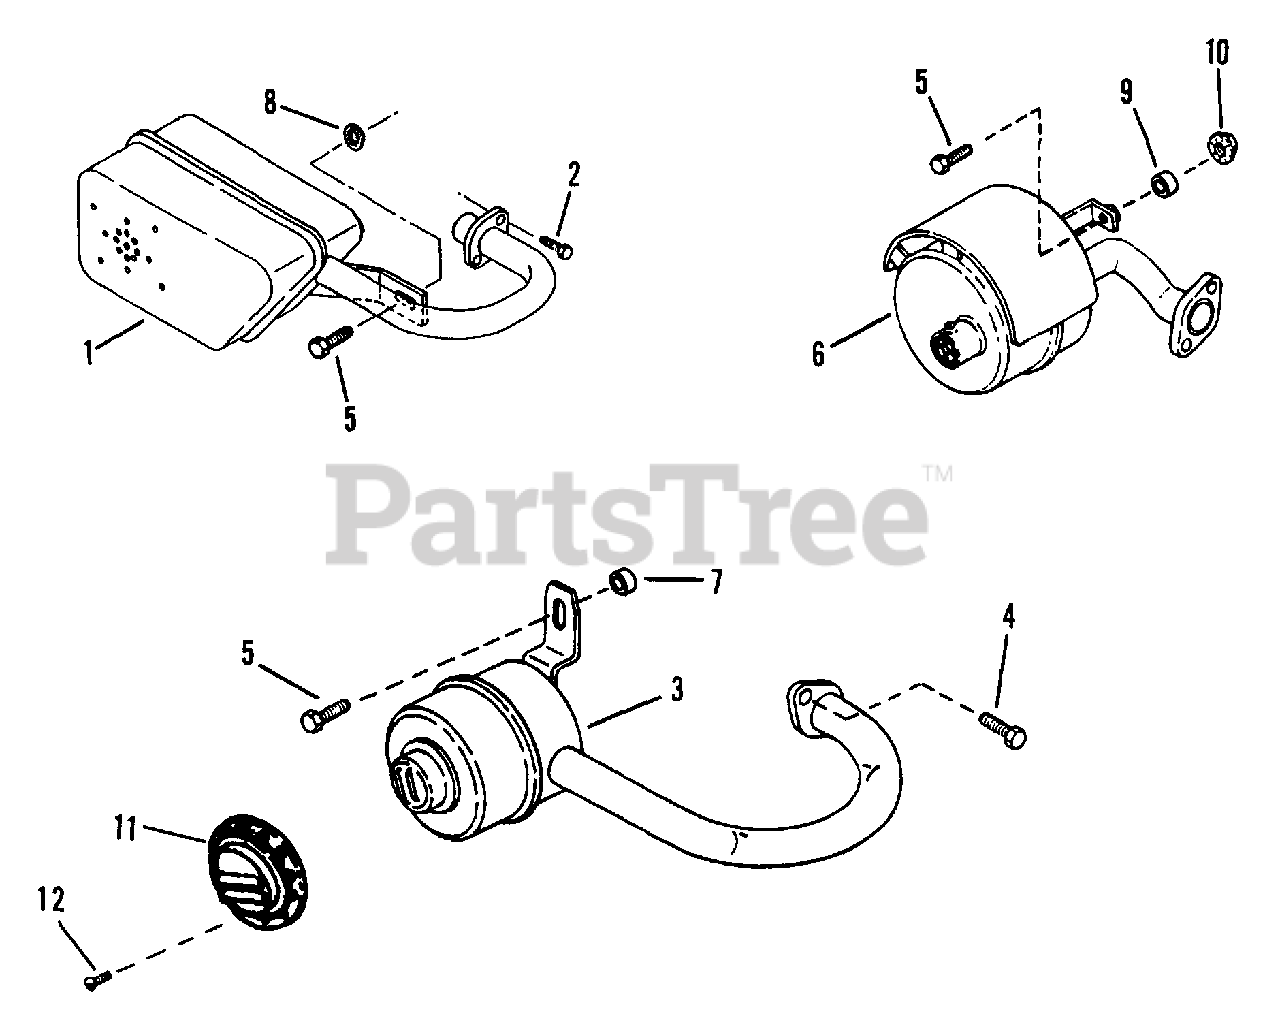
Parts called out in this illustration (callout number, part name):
1	MUFFLER
2	SCREW, 1/4-20 x 5/8" Hex Head Cap
3	MUFFLER
4	SCREW, 5/16-18 x 3/4" Hex Head Cap
5	SCREW, 1/4-20 x 3/4" Hex Head Cap
6	MUFFLER
7	SPACER
8	WASHER, 1/4 Internal Tooth Lock
9	SPACER
10	NUT, 5/16-18 Hex Flange Lock
11	DEFLECTOR, Heat
12	SCREW, #8 x 3/8
